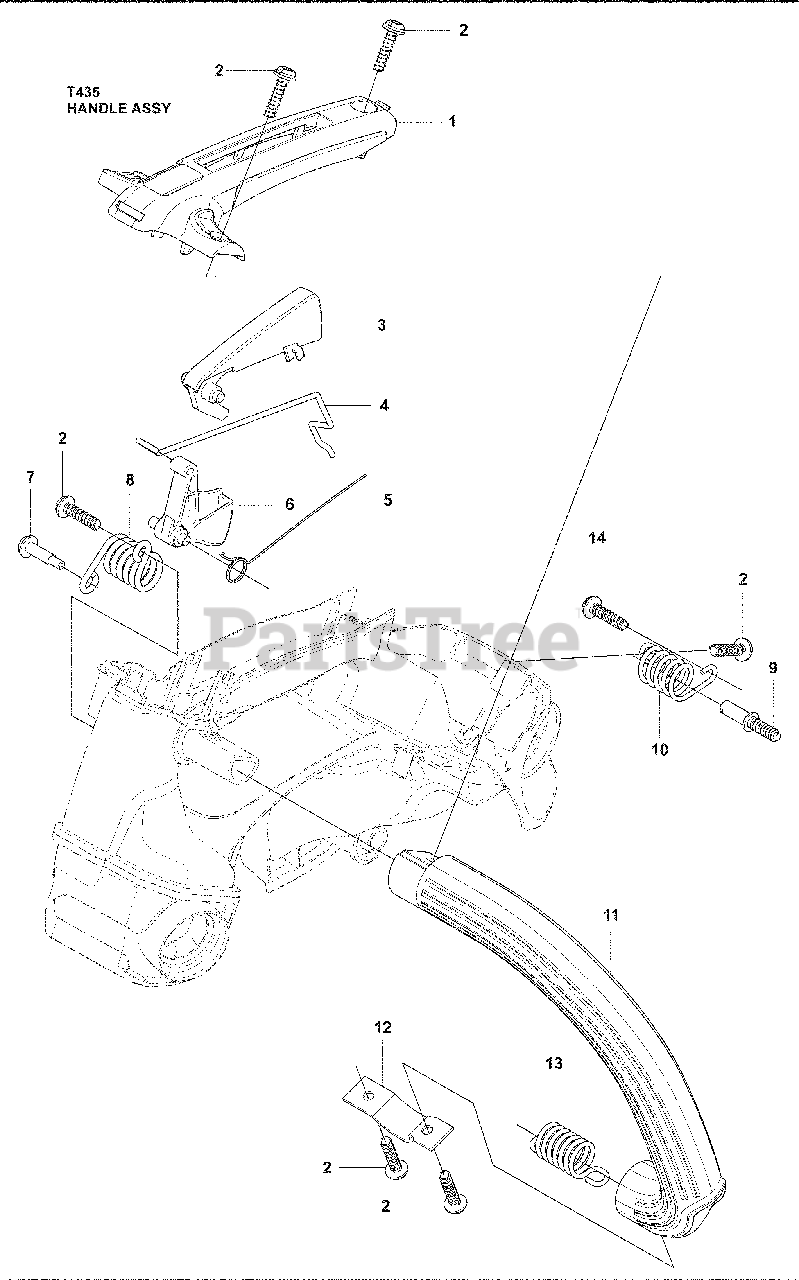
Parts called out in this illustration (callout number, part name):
1	Cover top handle
3	Throtlle guard
5	Spring
9	Bolt
11	Front handle
